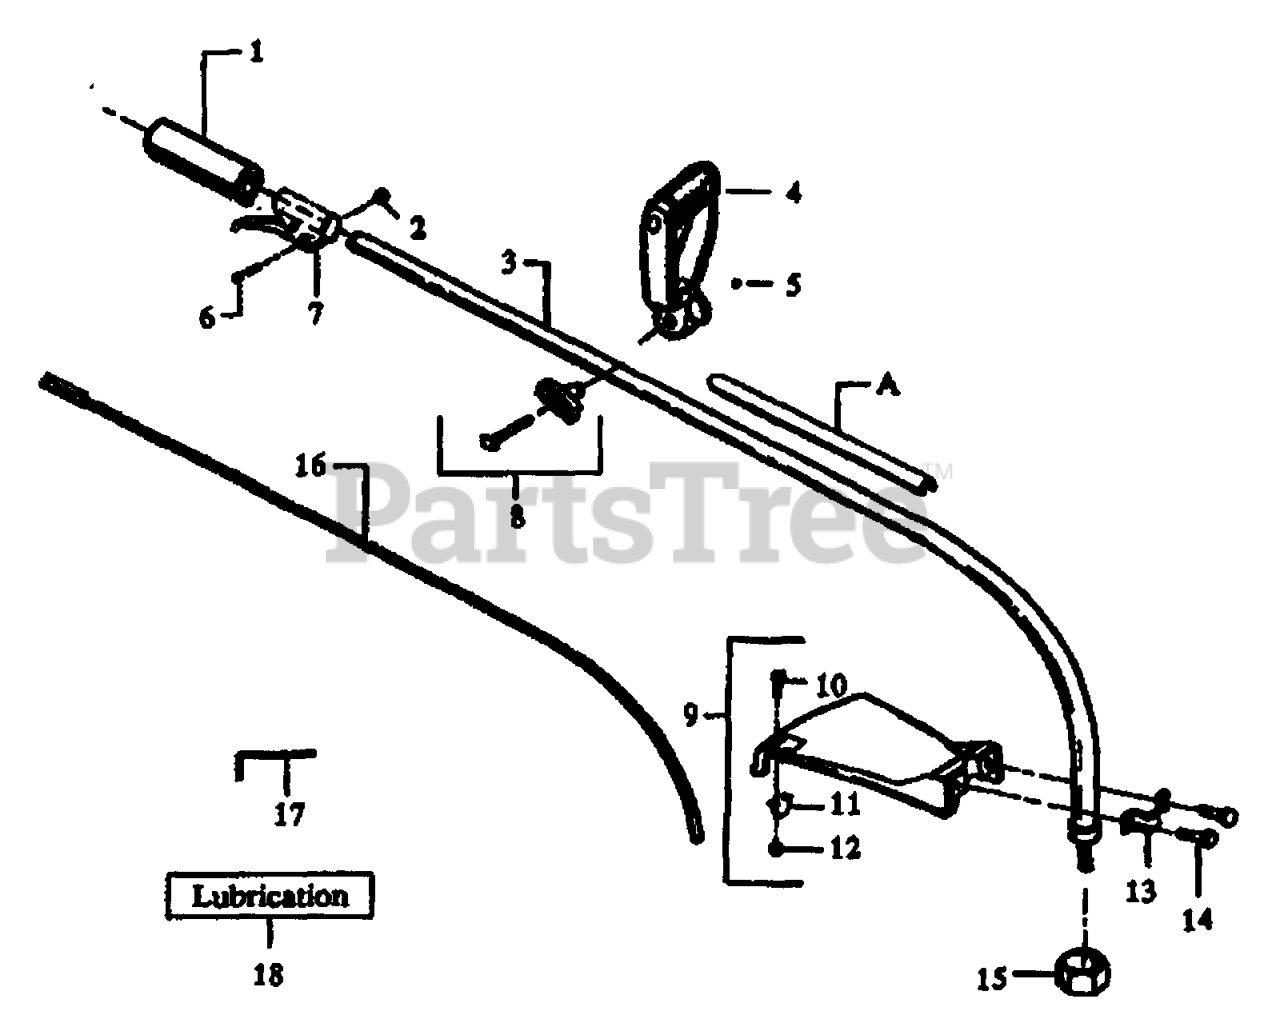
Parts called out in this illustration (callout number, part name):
1	GRIP-DRIVE SHAFT
2	LOCKNUT-HEX 10-24
3	ASSY-DRIVE SHAFT HSG(48
4	Handle Ass'y.
6	SCREW-10-24 X 1" (UNC)
7	ASSY-THROTTLE HOUSING
8	KIT "T" HANDLE
9	GUARD
11	LIMITER-LINE
13	BRACKET-SHIELD
14	SCREW-1/4-10X1-1/8 HEX
16	SHAFT-FLEX (48")
17	HEX KEY
18	GREASE-1/2 FL. OZ.
